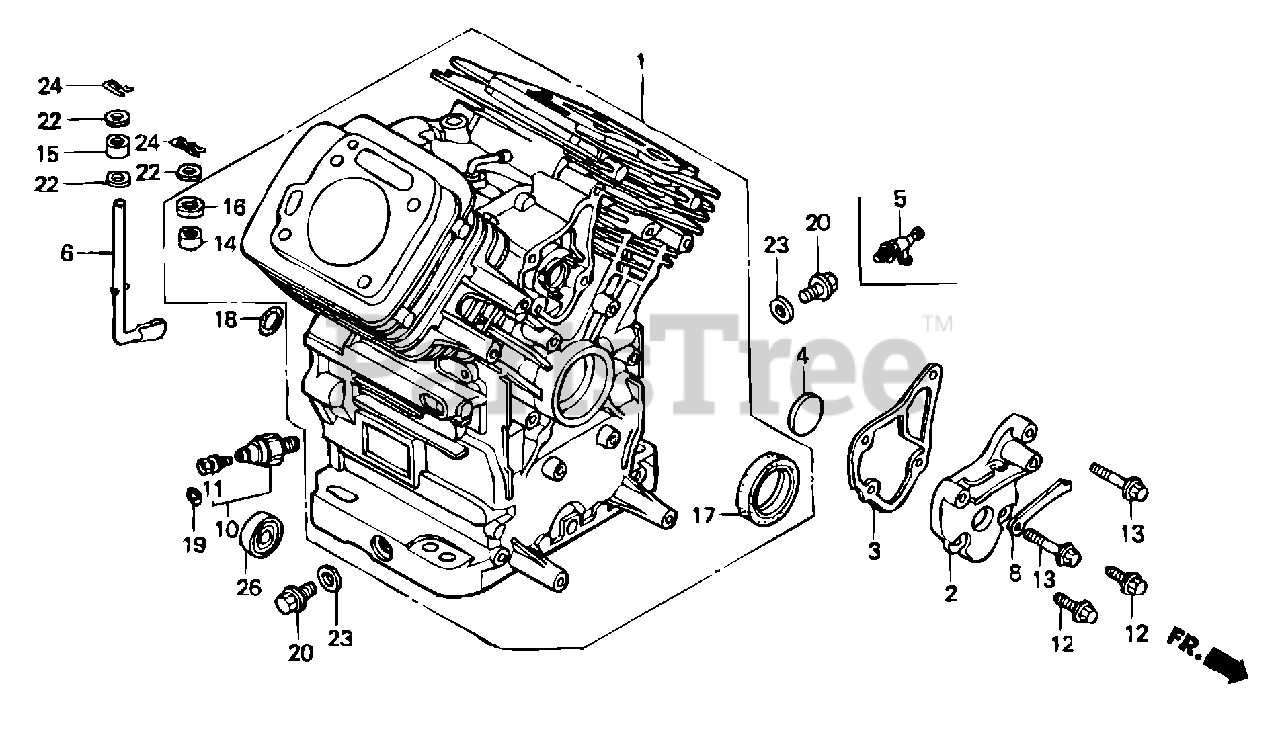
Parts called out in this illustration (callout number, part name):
1	Cylinder Assembly
2	Cover, Breather
3	Gasket, Breather Cover
4	Valve, Breather
5	Valve, Drain (14x1.5)
6	Shaft, Governor Arm
8	Clamp, Wire
10	Switch, Oil Pressure
11	Screw-washer (4x8)
12	Bolt, Flange (6x16)
13	Bolt, Flange (6x32)
14	Bearing, Needle (8x12.7x11.1)
15	Bearing, Needle (8x12x10)
16	Oil Seal (8x14x5)
17	Oil Seal (38x58x9)
18	O-ring (13x3.0)
20	Bolt, Drain Plug (14mm)
22	Washer, Plain (8mm)
23	Washer, Drain Plug (14mm)
24	Pin, Lock (8mm)
26	Bearing, Radial Ball (6003)
